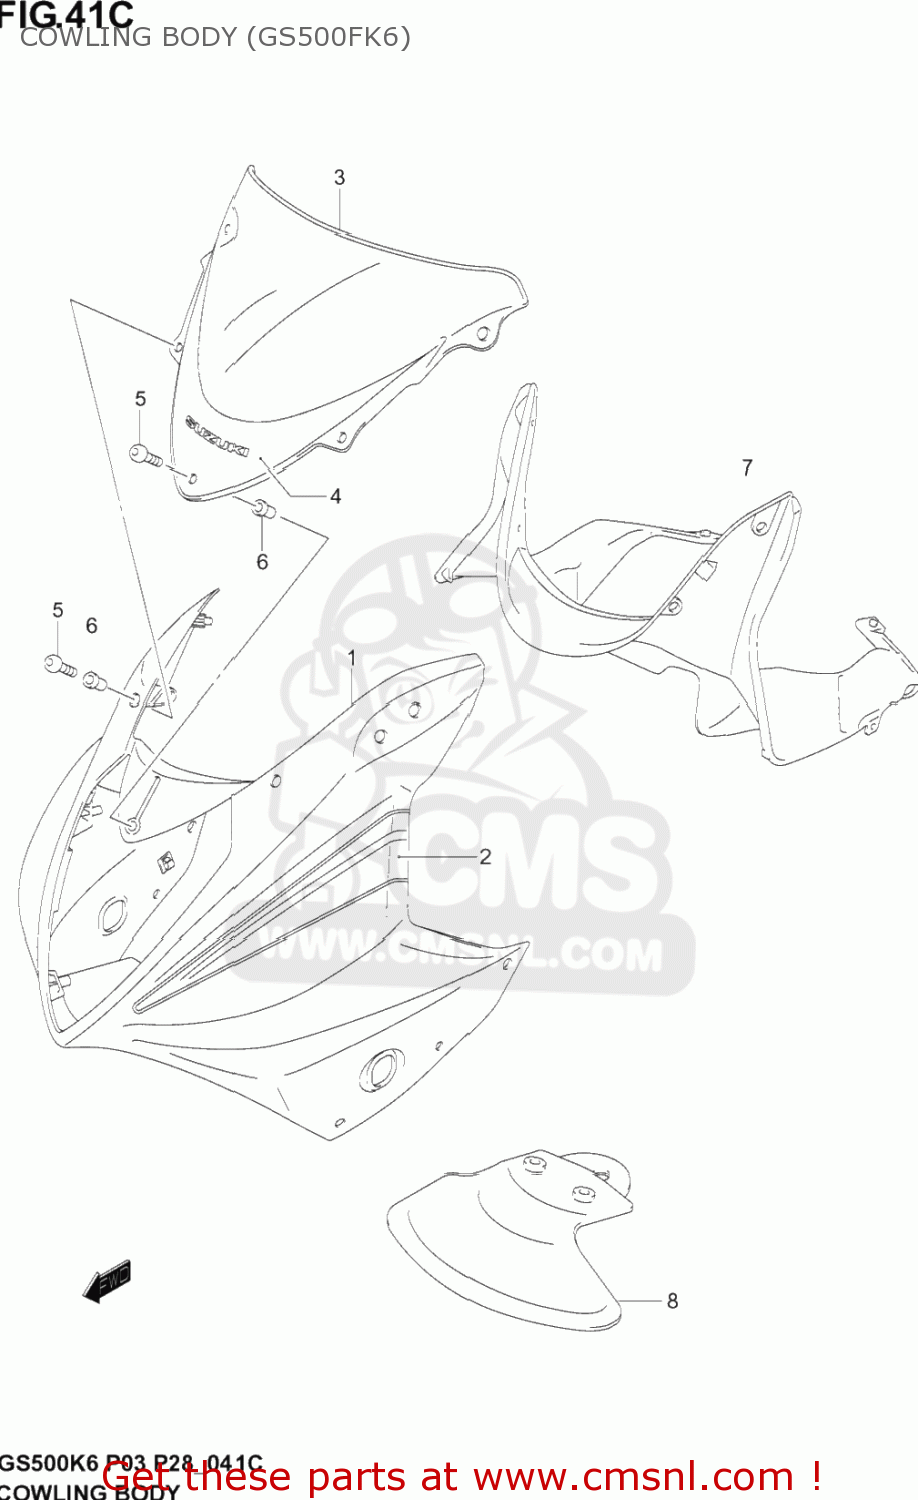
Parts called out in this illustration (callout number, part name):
1	COWLINGBODY BL
2	EMBLEM SET RH
3	WINDSCREEN
4	TAPE,WINDSCREEN
5	SCREW(5X18)
6	NUT
7	PANEL, FRONT
8	COVER,LOW.BRAC
